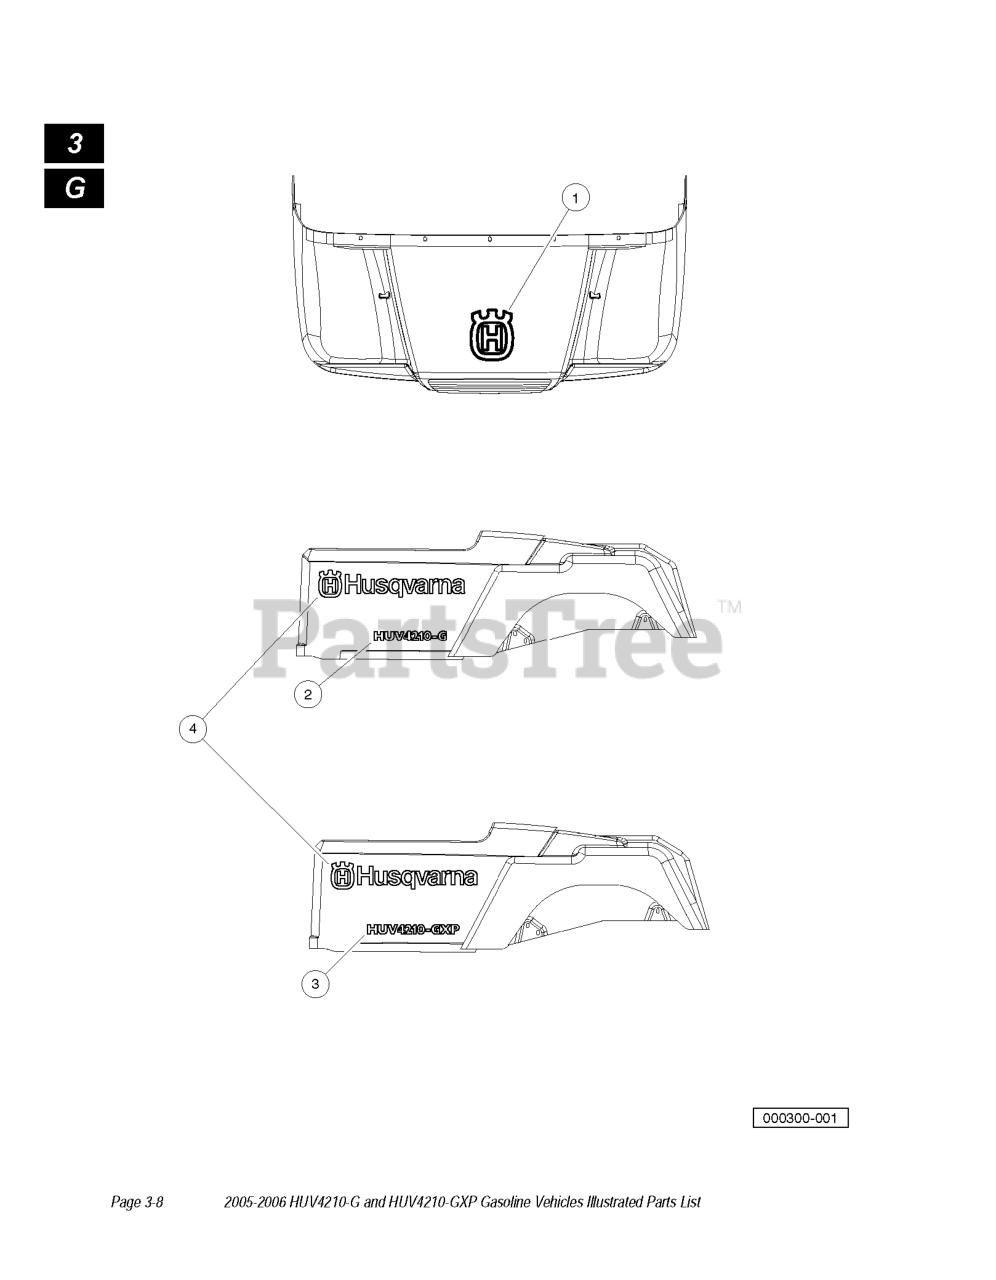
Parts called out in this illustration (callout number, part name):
1	DECAL HUSQ TOP
2	DECAL HUSQ SIDE G
3	DECAL, HUSQ, SIDE, GPLUS
4	DECAL, HUSQ, SIDE
